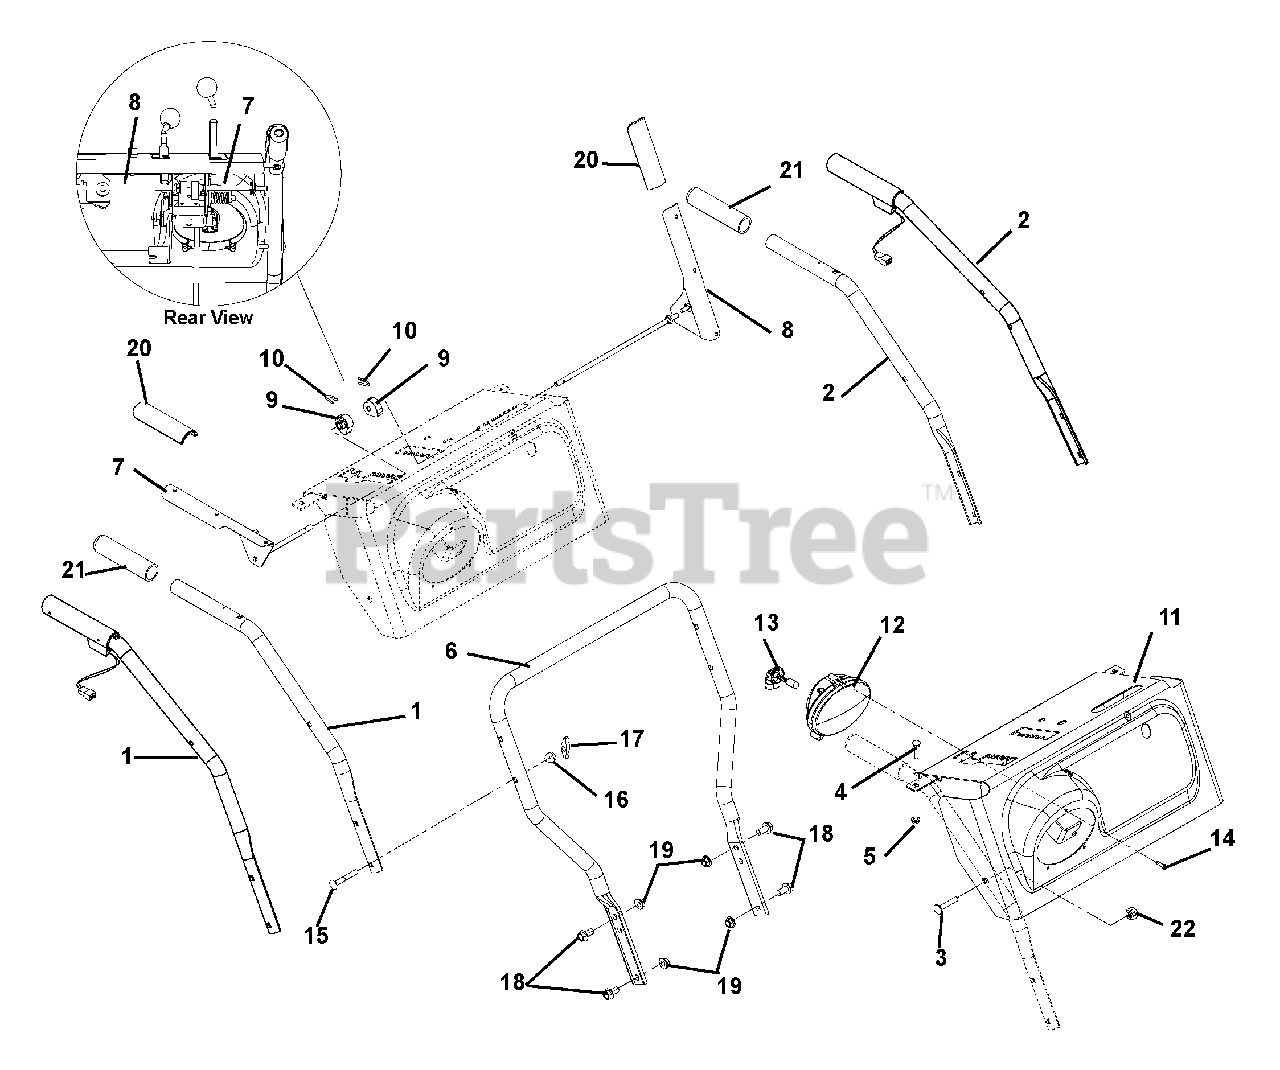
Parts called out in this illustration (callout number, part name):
1	HANDLEBAR, UPPER-RH
1	HANDLEBAR, UPPER RH-W/HW
2	HANDLEBAR, UPPER-LH
2	HANDLEBAR, UPPER LH-W/HW
3	@BLT-RDHDSQNK .31-18X1.75 G5YZ
4	BLT-RDHDXLSQNK.25-20X1.25 G5ZC
5	@NUT-LK-CTR .25-20 YWZC
6	HANDLEBAR, LOWER
7	LEVER, RH-ATTACHMENT
8	LEVER, LH-TRACTION
9	CAM, INTERLOCK
10	PIN, SPRING CLIP
11	PANEL-W/CONTROL DECAL
11	PANEL-W/CONTROL HW DECAL
11	PANEL-W/CONTROL 12V DECAL
11	PANEL-W/CONTROL BRUSH DECAL
12	HEADLIGHT ASSY,HALOGEN 862 37W
13	BULB, LIGHT-HALOGEN 37W/#862
14	SCR-TAP 10-16X.75 HI-LO PPH
15	@BLT-RDHDSQNK .31-18X2.25 G5YZ
16	SPACER, HANDLEBAR
17	KNOB - WING .312-18 UNC
18	BLT-SERHFWH .38-16X.75 YWZC
19	@NUT-LK-TOP-FLG .38-16 YWZC
20	GRIP, CLUTCH LEVER, LH AND RH
21	HANDLE GRIP
22	@NUT-LK-CTR .31-18 YWZC
